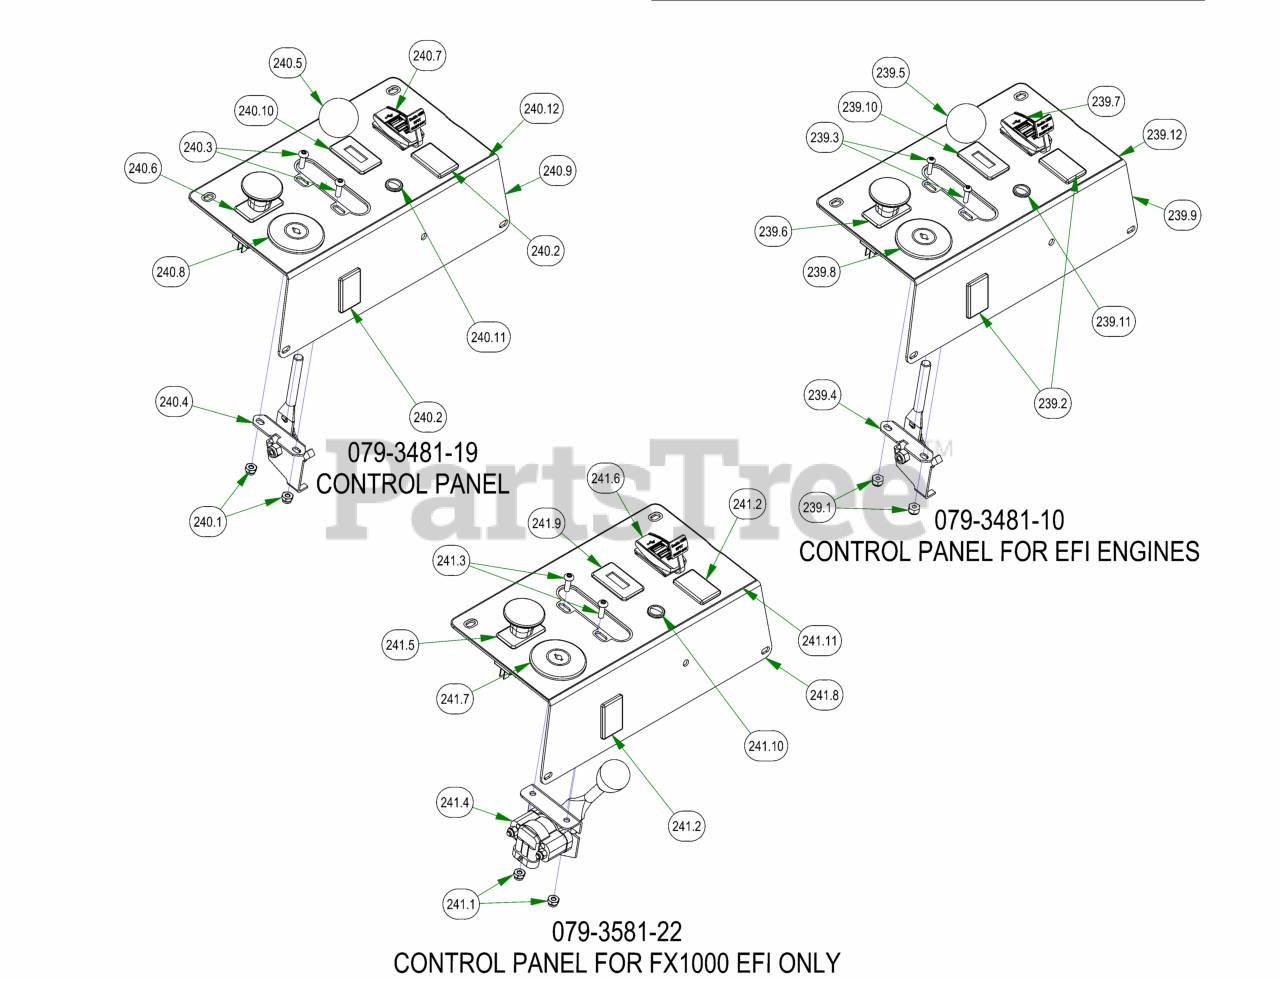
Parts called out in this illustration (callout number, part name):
239	Rebel/Rogue EFI Control Panel Assy
239.1	10-24 Nylon Insert Locknut Zinc Orange Nylon
239.2	Light Plug
239.3	10-24 X 5/8 BS Button Head Bolt
239.4	Universal Throttle Head - 2012
239.5	Throttle Knob
239.6	PTO Switch
239.8	Ignition Switch
239.9	2022 Rebel Control Panel
239.10	Tachometer
239.12	2022 Rebel/Rogue Control Panel Decal
240	Rebel/Rogue Control Panel Assy
240.1	10-24 NYLON INSERT LOCKNUT ZINC
240.2	Light Plug
240.3	10-24 X 5/8 BUTTON SOCKET CAP SCREW 18-8 STAINLESS STEEL
240.4	Universal Throttle Head - 2012
240.5	Throttle Knob
240.6	PTO Switch
240.8	Ignition Switch
240.9	2022 Rebel Control Panel
240.10	Tachometer
240.12	2022 Rebel/Rogue Control Panel Decal
241	Rebel/Rogue Control Panel Assy-Drive by Wire
241.1	10-24 NYLON INSERT LOCKNUT ZINC
241.2	Light Plug
241.3	10-24 X 5/8 BUTTON SOCKET CAP SCREW 18-8 STAINLESS STEEL
241.4	Kawasaki \ Kohler Drive By Wire
241.5	PTO Switch
241.7	Ignition Switch
241.8	2022 Rebel Control Panel
241.9	Tachometer
241.11	2022 Rebel/Rogue Control Panel Decal
